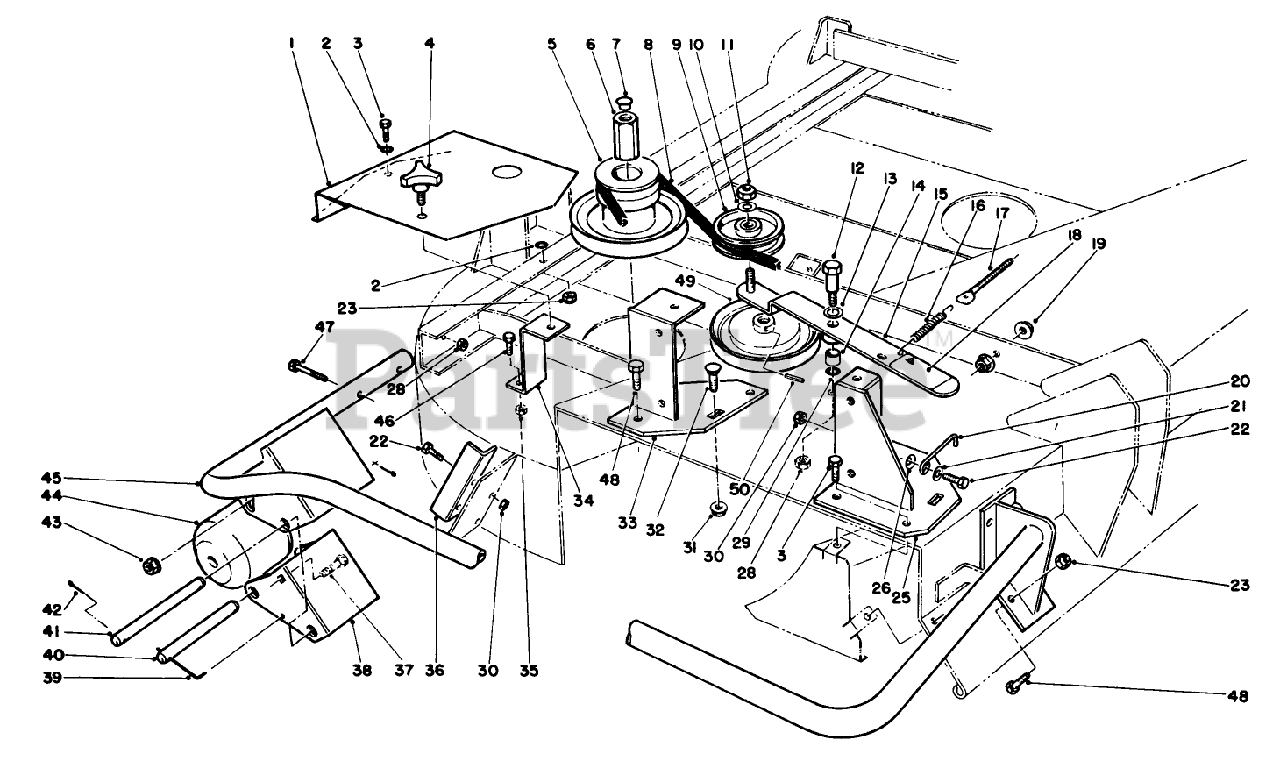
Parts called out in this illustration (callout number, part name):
1	Cover-Deck, R.H.
2	WASHER-PLAIN
3	SCREW-HH
5	Pulley-Splined
6	NUT-PULLEY
7	NUT-COVER
8	V-BELT
9	PULLEY-IDLER
10	WASHER-FLAT
11	NUT-LOCK, NI
12	SCREW-PIVOT
13	WASHER-THRUST
14	BUSHING
15	Assembly-Arm (Incl. Ref. #14 & 18)
16	SPRING-TRACTION
17	ROD-THREADED
18	DECAL-WARNING
19	NUT-HF
21	WASHER-FLAT
22	SCREW-HH
23	NUT-LOCK, NI
25	BRACKET WA - RH
26	WASHER-BELLEVILLE
28	NUT-LOCK, NI
29	WASHER-THRUST
30	NUT-LOCK, NI
31	NUT-HHF, WHIZ
32	SCREW-CARR
33	BRACKET-LH
34	Support-Cover
35	Nut
36	DEFLECTOR STOP B
37	SCREW-CARR
38	Bracket-Roller
39	PIN - SPECIAL
40	SHAFT
42	PIN-COTTER
43	NUT-FLANGE
44	ROLLER - 4" DIA
45	Bumper
47	SCREW-HH
48	SCREW-HH
49	Pulley-Gear Box
50	PIN-ROLL, SLOTTED
